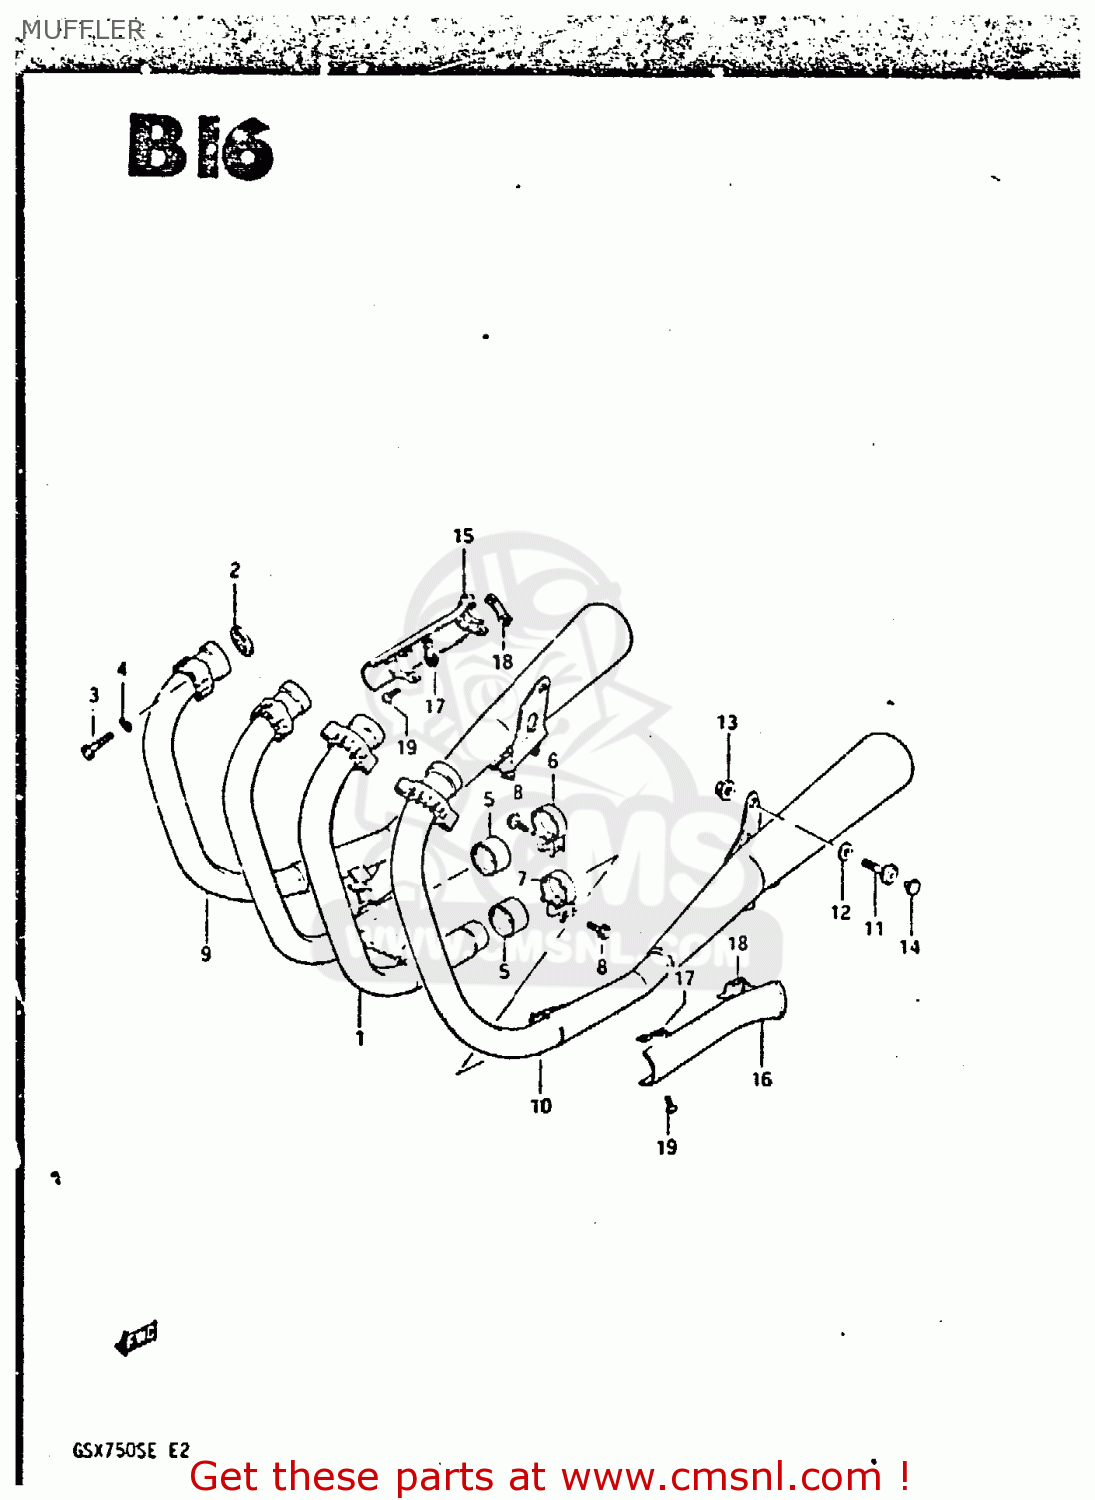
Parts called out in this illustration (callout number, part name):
1	PIPE, EXHAUST CENTER
2	GASKET,EXHAUST PIPE (NAS)
3	BOLT 8X40
4	WASHER,LOCK,8.
5	CONNECTOR,MUFFLER
6	CLAMP,MUFFLER CONNECTOR
7	CLAMP,MUFFLER CONNECTOR
8	BOLT
9	MUFFLER,RH.
10	MUFFLER, LH
11	BOLT
12	WASHER
13	NUT
14	CAP
15	COVER,MUFFLER,RIGHT
16	COVER,MUFFLER,LEFT
17	CLAMP,MUFFLER COVER
18	CLAMP,MUFFLER COVER
19	SCREW
